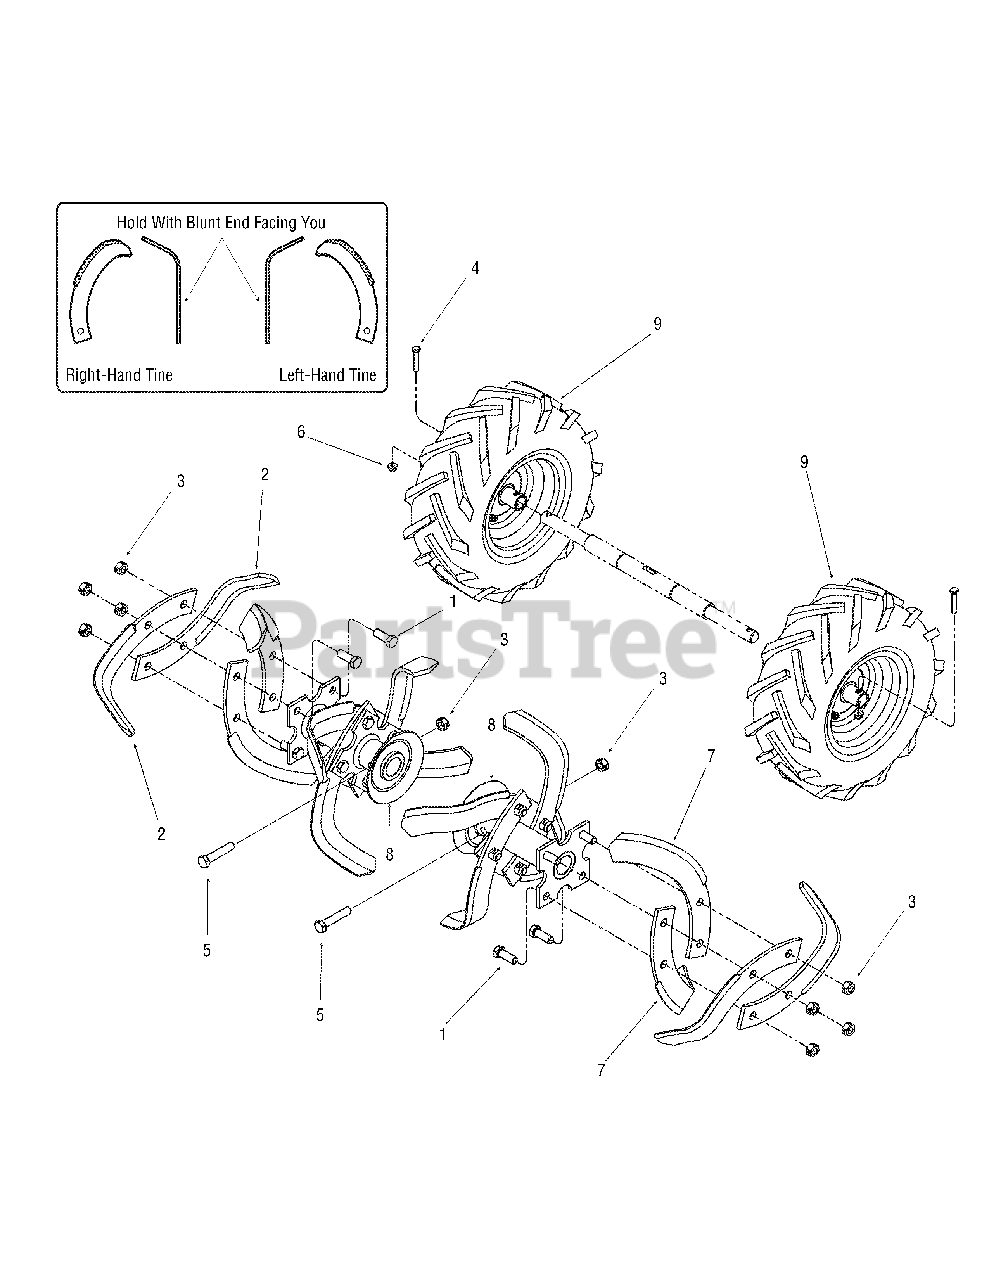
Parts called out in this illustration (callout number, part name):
1	Hex Hd. Screw, 3/8-16 x 1 (Specify Grade 5 if ordering part locally.)
3	Hex Locknut, 3/8-16
4	Hd. Screw, 1/4-20 x 1.5
5	Hex Hd. Screw, 3/8-16 x 2, Grade 8
6	Hex Locknut, Flange, 1/4-20
8	Tine Holder. For left and right sides
9	Wheel Assembly, 13 x 5 x 6
